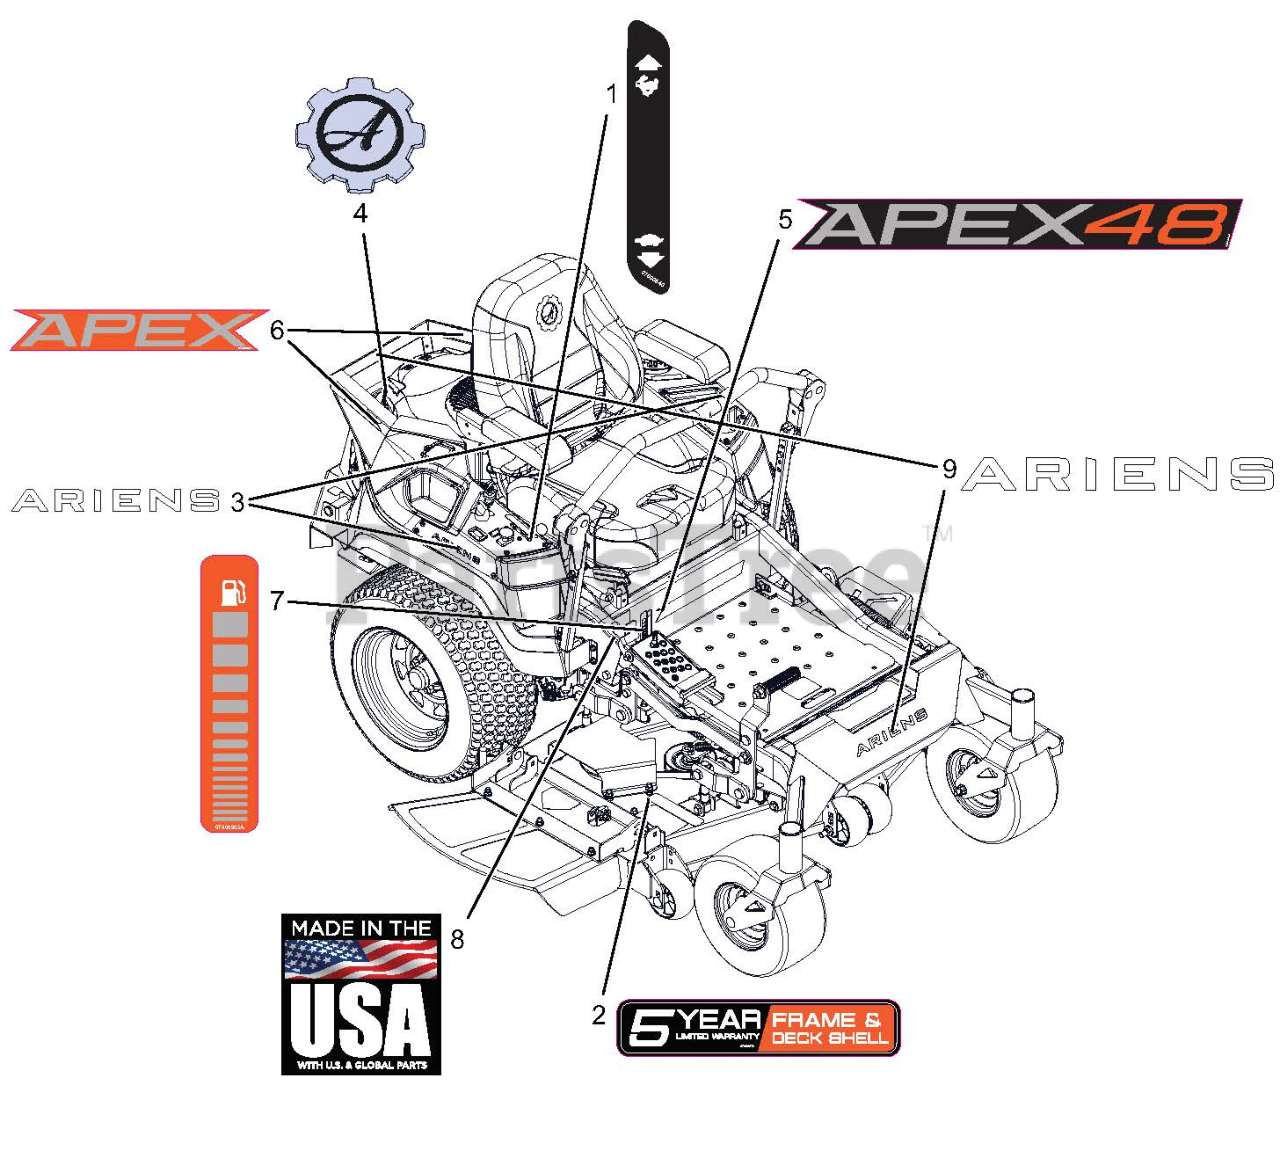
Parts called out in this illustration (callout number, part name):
1	DECAL, DASH DECAL
2	DECAL, DECK 5 YEAR-ARIENS
3	DECAL, ARIENS (6.50")
4	DECAL, ARIENS-GEAR BADGE -THK
5	DECAL, 48" APEX KICKPLATE
6	DECAL, APEX FENDER
7	DECAL, ARIENS FUEL LEVEL
8	DECAL, MADE IN USA
9	DECAL - ARIENS 9.625"
